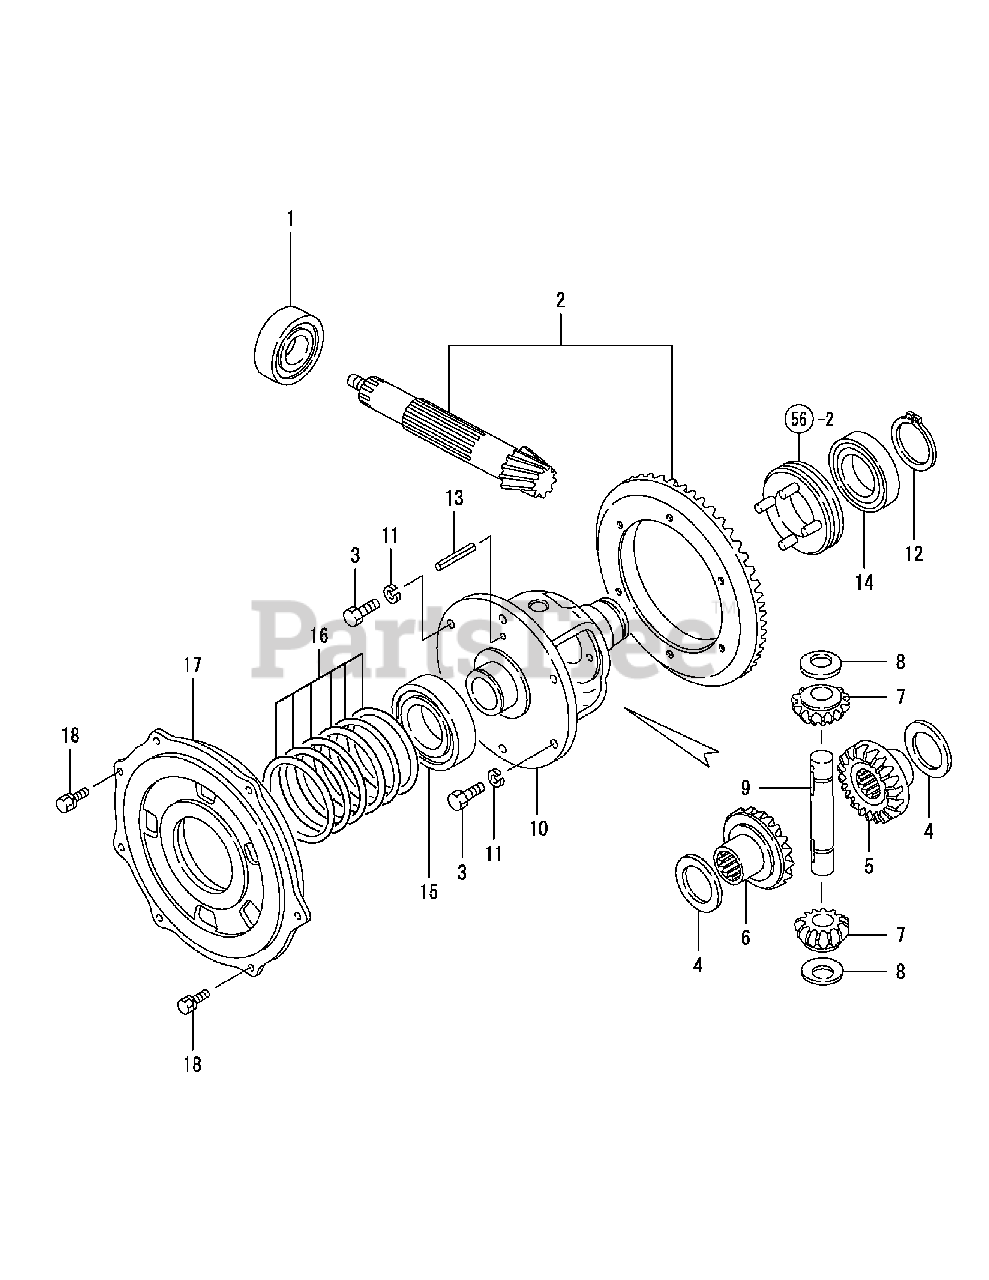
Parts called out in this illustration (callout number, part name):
1	BEARING 6307R SH2
2	GEAR W/COUNTERSHAFT
4	WASHER, DIFFERENTIAL
5	GEAR, DIFFERENTIAL
6	GEAR, DIFFERENTIAL
7	PINION, DIFFERENTIAL
8	WASHER, DIFFERENTIAL
9	SHAFT, DIFFERENTIAL
10	HOUSING, DIFF.
11	SPRING WASHER 10
13	SPRING PIN 6X50
17	CARRIER,DIFFERENTIAL
